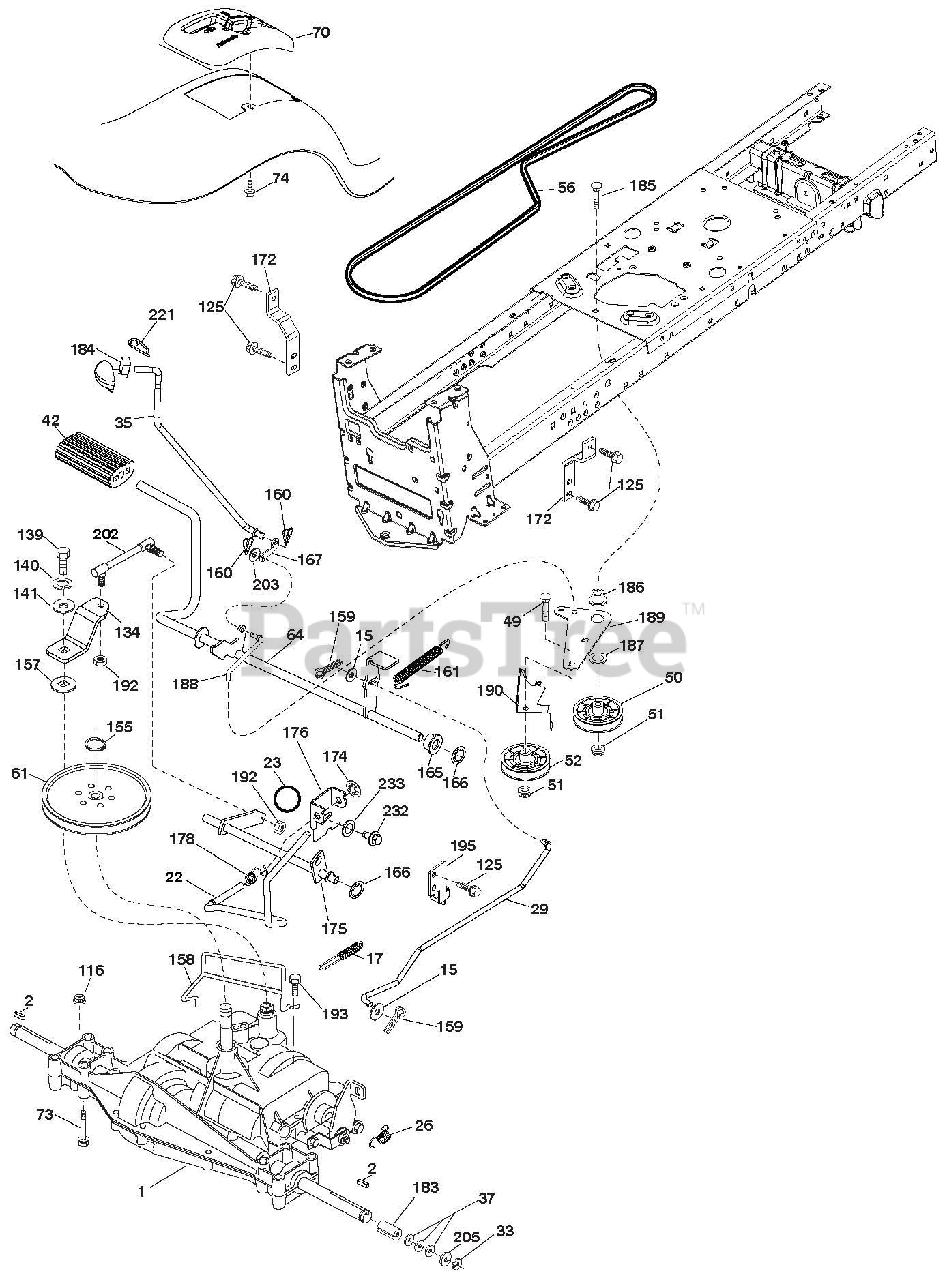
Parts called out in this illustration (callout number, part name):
2	KEY.SQUARE.2.0 X .1845/.1865
15	WASHER.13/32 X 13/16 X 16 GA.
17	SPRING.BRAKE.PEERLESS/D6800.TX
22	ROD.SHIFT.FENDER.TLT.2006
26	SPRING.BRAKE.RTN.GR DR.TEX.006
29	ROD.BRAKE.PEERLESS/D6800
33	E-RING.#5133-75
35	ROD.BRAKE.PARKING.LT.TEX
37	WASHER.25/32 X 1 1/4 X 16 GA.
42	COVER PEDAL BLK ROUND
49	BOLT.RDHD.3/8-16UNCX1-3/4.GR5
50	IDLER.FLAT.910"OFFSET
51	Nut, Hex, Flangelock 3/8-16
52	IDLER.V-GROOVE.910"OFFSET
56	V-BELT.DRV.97.40"PMST/DANA
61	PULLEY.TRANSAXLE.18/20"TIRES
64	SHAFT ASM.PEDAL.BRAKE CONTROL
70	CONSOLE SHIFT
73	BOLT 5/16-18 X 2 1/2 G.5
74	SCREW.HEX.WSH.HI-LO.1/4X1/2UNC
116	Nut, Lock Hex Flange 5/16-18 u
125	SCREW.5/16-18X3/4.SMGML.TAP/BL
134	ASM SHIFT
139	BOLT.1/4-28 UNF.GR8.W/PATCH
140	Washer, Lock 1/4
141	WASHER.9/32 X 3/4 X 10 GA.
155	Ring, Retainer
157	WASHER.PLATE.SHF..388 SQ.HOLE
158	KEEPER.T/A.PMS/D4360/D680.1820
159	PIN.COTTER.1/8 X 3/4.CAD.
160	RETAINER.CLIP(M).DIA.290
161	SPRING.RETURN.CLUTCH.6.75
165	BUSHING.SHAFT.BRAKE.HAND CONTR
166	NUT PUSH .625
167	LATCH.BRAKE.PARKING
172	STRAP.TRQ.LH.GEAR DRIVE.LT.TEX
174	NUT.PUSH..500
175	SHAFT ASM. SHIFT GEAR DRIVE
176	ARM.CLEVIS.ROD.SHIFT
178	SPRING.SHIFT.GT.2006
183	SPACER.AXLE.HYDRO/PEERLES
184	HANDLE.PARKING
185	BOLT.RDHD.3/8-16UNC X2-3/4 GR5
186	SPACER.RETAINER
187	WASHER.13/32 X 2 X 10 GA.
188	LINK.CLUTCH.GROUND DRIVE
189	BELLCRANK.GROUNDRIVE.NSTG/NSTL
190	KEEPER.BELLCRANK.DRIVE.GROUND
192	NUT.LOCK.CENTER.1/4-28 FNTHD.
193	SCREW.5/16-18X3/4.SMGML.TAP/R
195	BRACKET.ROD.BRK.PEERLESS/D6800
203	Washer 11/32 x 11/16 x 16 Ga.
205	WASHER.25/32 X 1-5/8 X 16GA.
221	RETAINER.SPRING.CLIP.HANDLE
232	BOLT.FIN HEX.7/16-14X1 GR5
233	WASHER.SERRATED
